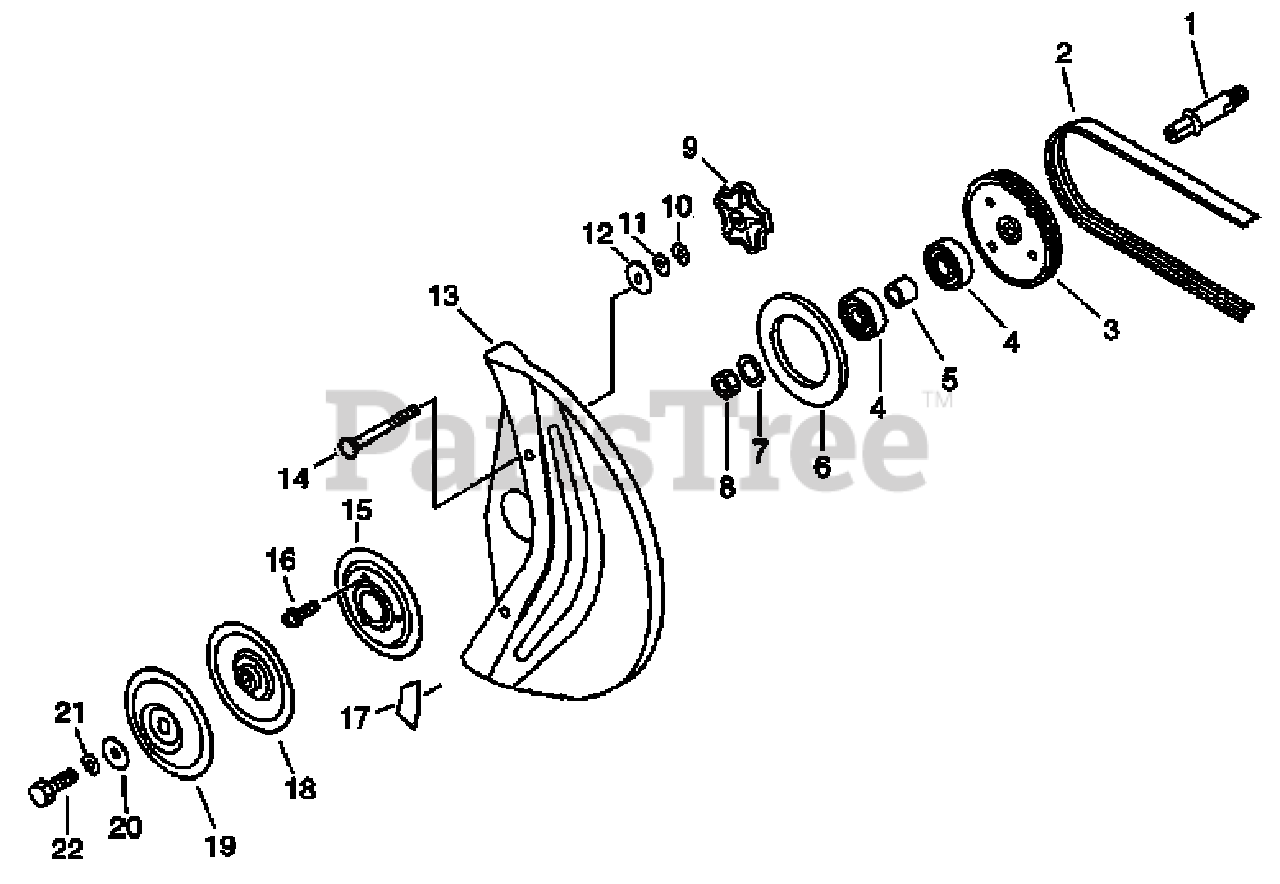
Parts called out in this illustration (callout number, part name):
1	SHAFT, CUTTER
2	BELT
4	BEARING, BALL - 6202
7	WASHER - 10
8	NUT - 10
9	KNOB, FASTENER
10	LOCKWASHER - 8
11	WASHER - 8
12	WASHER - 8
13	COVER, CUTTER
14	BOLT - 8
15	PLATE, CUTTER COVER
16	SCREW - 4X10
17	LABEL - CAUTION
18	FLANGE, CUTTER
19	FLANGE, CUTTER
21	LOCKWASHER - 10
22	BOLT - 10
